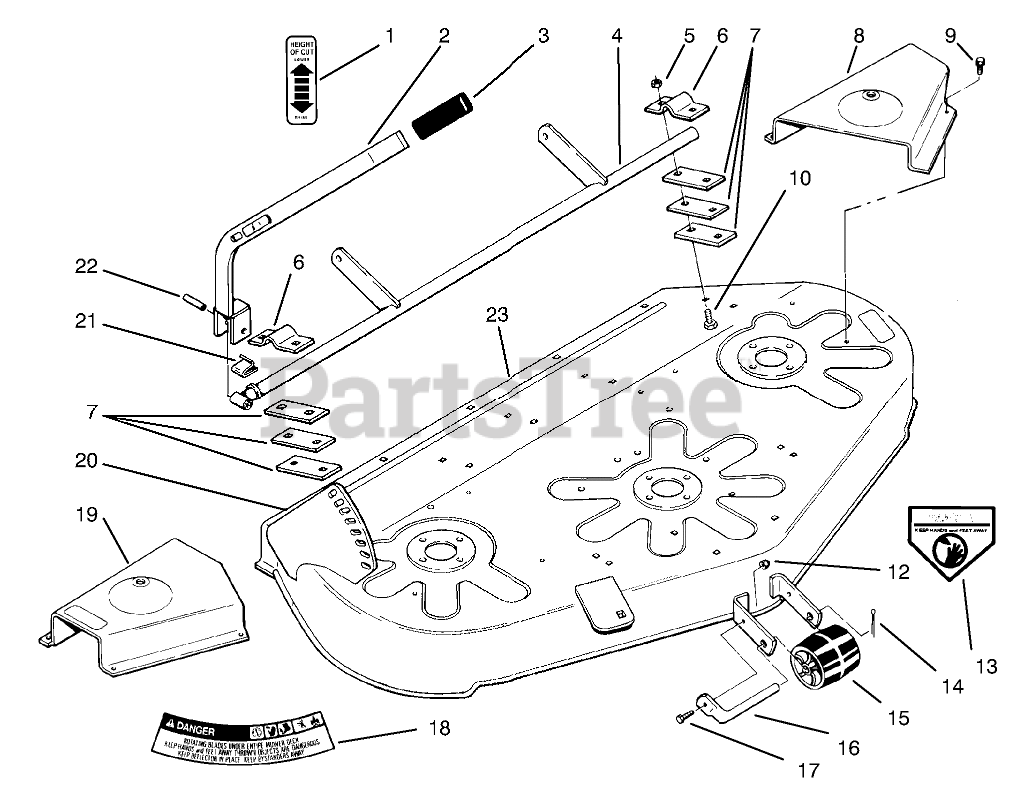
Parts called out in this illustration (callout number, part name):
1	DECAL-HOC
2	Lever
4	Lift Support
5	NUT-LOCK, NI
7	Bar
8	Belt Cover LH
9	SCREW-HWH
10	SCREW-CARR
12	NUT-LOCK, NI
13	DECAL-DANGER
14	PIN-COTTER
15	Roller
16	ROLLER-SHAFT
17	SCREW-HH
18	DECAL - DANGER
19	Belt Cover RH
20	QUADRANT 42RY MOWER
21	CLIP-SPRING
22	SPIROL PIN 3/8X1 1/2
23	Deck Ass-y (Incl. Ref. #13, & 18)
